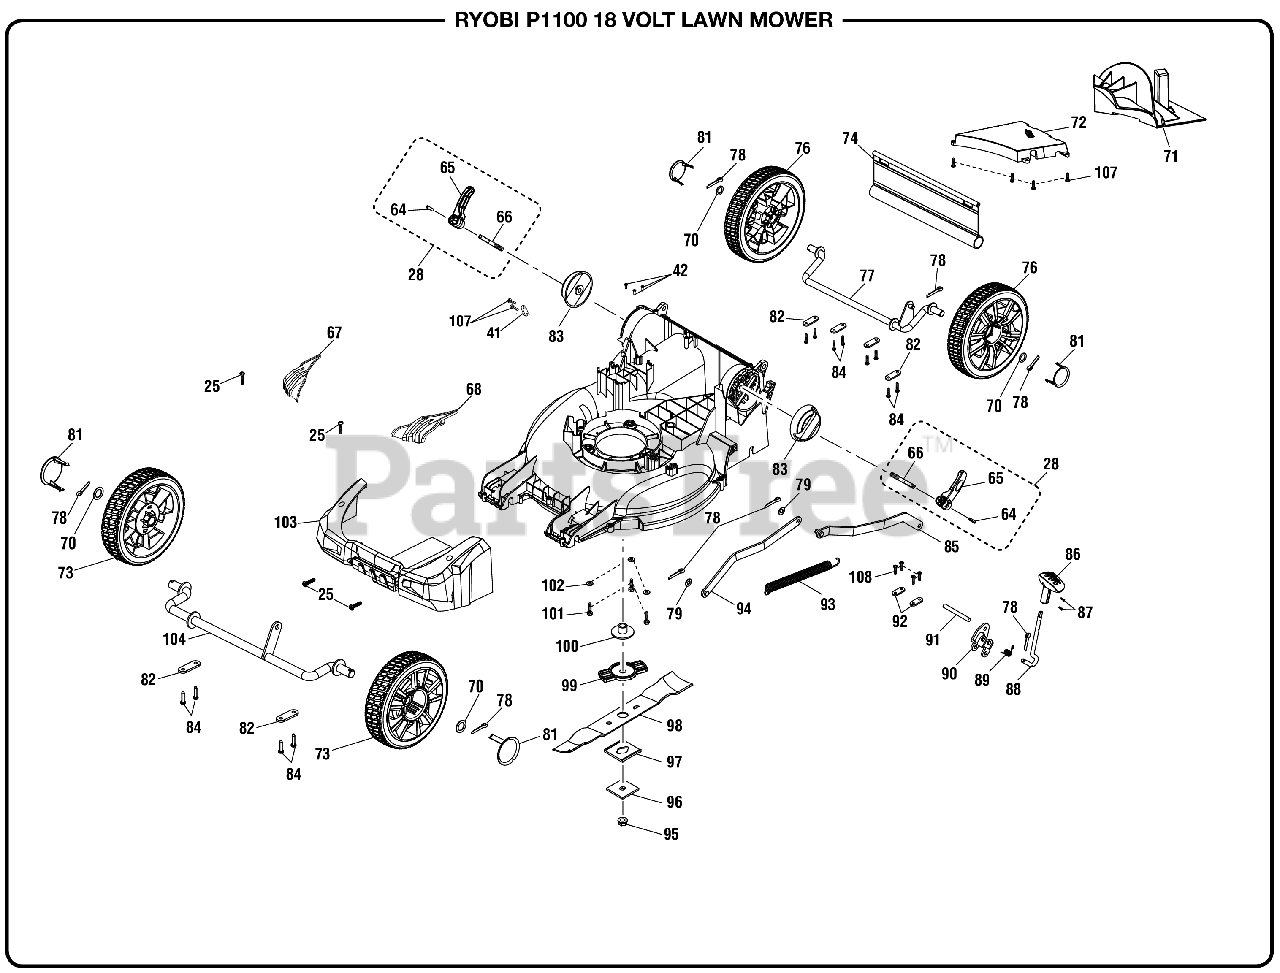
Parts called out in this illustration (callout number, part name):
25	Screw (M4 x 20 mm, T20 Torx Pan Hd. S.T.)
28	Handle Lock Assembly
41	Wire Press Plate
42	Screw (M4.2 x 12 mm, T20 Torx Pan Hd.)
64	Spring Pin
65	Adjust Height Handle
66	Quick Lock Press Block
67	Grass Protector (Right)
68	Grass Protector (Left)
70	Washer (ID13.5 x OD20 x 1t)
71	Mulching Plug
72	Rear Cover
73	Front Wheel w/Bearing & Cap 6 in.
74	Rear Skirt
76	Rear Wheel w/Bearing & Cap 8 in.
77	Rear Wheel Axle
78	Cotter PinÏ? (2.5)
79	Washer (ID8.4 x OD18 x 1t)
81	Wheel Cover (Before Serial Number EU18234D020307)
82	Axle Pressure Plate
83	Quick Lock Press Block
84	Screw (M4 x 18 mm, T20 Torx Pan Hd.)
85	Rear Lift Rod
86	Height Adjustment Handle
87	Screw (M3 x 9 mm, Flat Hd.)
88	Height Adjustment Lever
89	Torsion Spring (Height Adjustment)
90	Adjustment Height Bracket
91	Axle (Height Adjustment)
92	Pressure Plate (Height Adjustment)
93	Rentention Spring
94	Front Lift Rod
95	Blade Nut (M10 x 1.25, Hex Flange Hd.)
96	Metal Blade Retainer
98	Blade (16 in.)
99	Blade Holder
100	Motor Shaft Bushing
101	Bolt (M6 x 26 mm, Hex Hd.)
102	Washer (ID6.2 x OD15 x 0.08t)
104	Front Wheel Axle
107	Screw (M4 x 16 mm, T20 Torx Pan Hd.).
108	ST SCREW,STEEL CH M4.0X1.8 PH TORX
